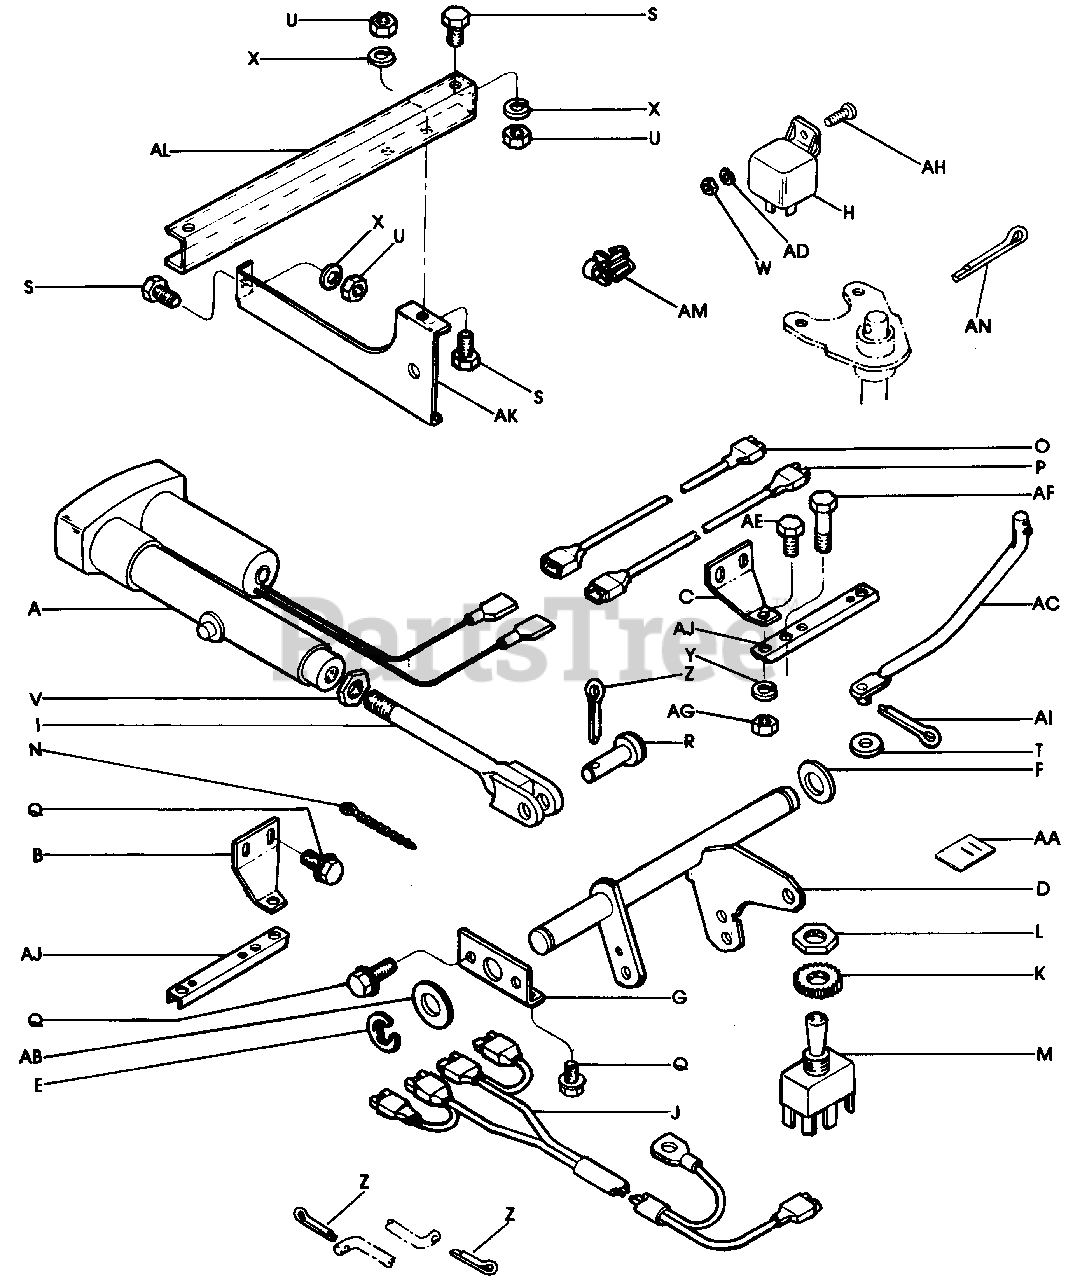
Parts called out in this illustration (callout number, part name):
A	Power Lift Assembly
B	Brace-R.H.
C	Brace-L.H.
D	Lift Shaft Assembly
E	"E" Ring
F	Washer
G	Bracket-Lift
H	Relay
I	Rod Assembly
J	Wiring Harness
K	Knurled Nut
L	Hex Nut
M	DPDT Switch
N	Nylon Beaded Tie
O	Wire-Yellow-37"
P	Wire-Red-37"
Q	Hex Hd. Thread Forming Screw 5/16-18 x 1/2
R	Clevis Pin
S	Cap Screw, Hex Hd. 5/16-18 x 3/4 Plated, Grade 5
T	Washer, Flat SAE 5/16 Plated
U	Nut, Hex 5/16-18 Plated
V	Nut, Hex 5/8-18 Plated
W	Nut, Hex #10-24 Plated
X	Washer, Spring Lock 5/16 Plated
Y	Washer, Spring Lock 3/8 Plated
Z	Pin, Cotter 1/8 x 3/4 Plated
AA	Sticker-Electric Lift
AC	Speed Control
AD	Washer. External Tooth Lock #10 Plated
AE	Cap Screw, Hex Hd. 3/8-16 x 3/4 Plated, Grade 5
AF	Cap Screw, Hex Hd. 3/8-16 x 2 Plated, Grade 5
AG	Nut, Hex 3/8-16 Plated
AH	Machine Screw, Phillips Pan Hd. #10-24 x 1/2 Plated
AI	Pin, Cotter 3/32 x 3/4 Plated
AJ	Support-Footrest
AK	Support
AL	Hanger
AM	Wire Clip
AN	Pin, Cotter 1/8 x 1-1/8 Plated
